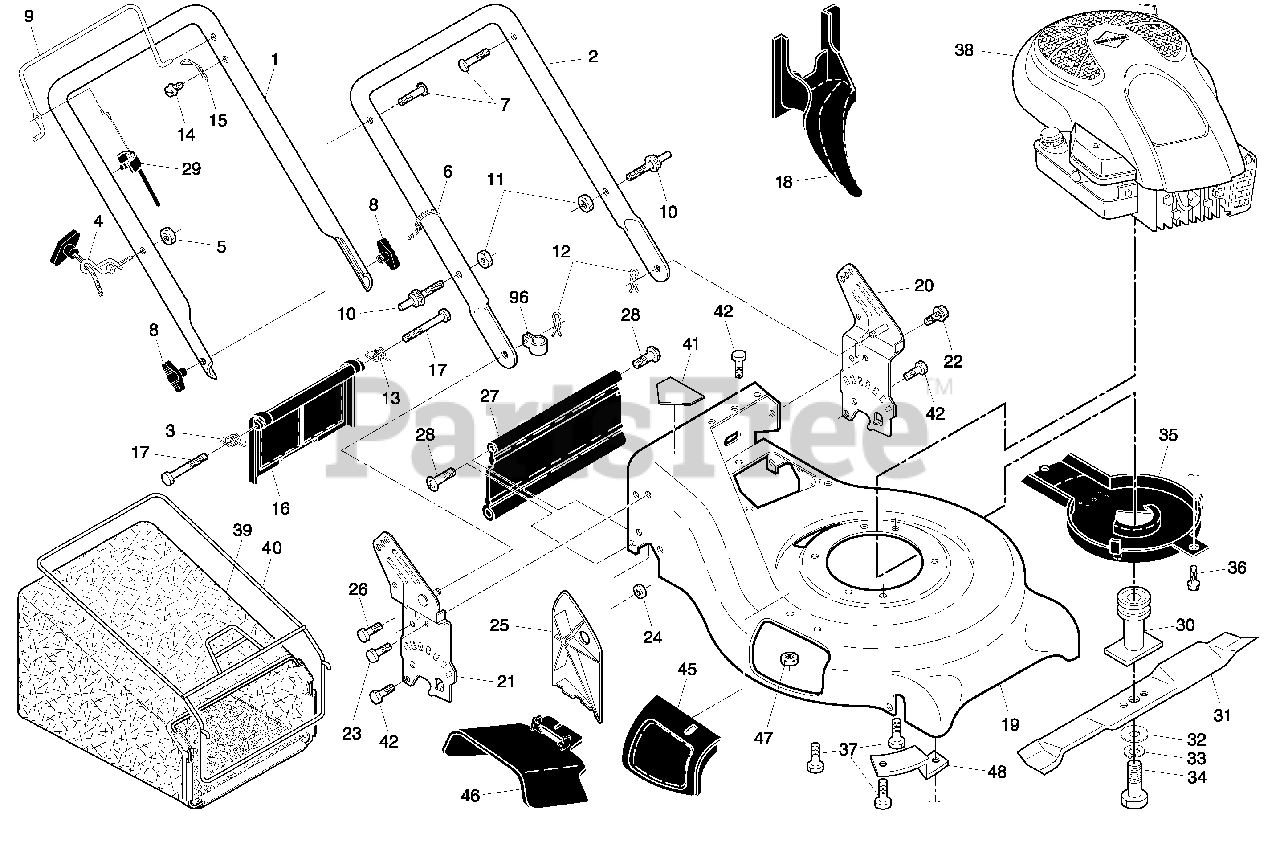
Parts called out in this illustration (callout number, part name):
1	Handle, Upper
2	Handle, Lower
3	Spring, Rear Door, RH
4	Rope Guide
5	Nut, Hex, with Lockwasher Insert 1/4-20
6	Wire, Tie
7	Bolt, Handle 5/16-18 x 2-5/8
8	Knob, Handle
9	Control Bar
10	Pin, Handle
11	Nut, Hex
12	Cotter, Hairpin
13	Spring, Rear Door, LH
14	Screw
15	Bracket, Upstop
16	Rear Door Assembly
17	Bolt, Rear Door
18	Plug, Mulcher
19	Kit, Housing
20	Handle Bracket Asembly, LH
21	Handle Bracket Assembly, RH
22	Screw, Hex Washer Head
23	Bolt, Hex Head 5/16-18 x 5/8
24	Nut, Hex, with Lockwasher Insert 5/16-18
25	Baffl e, Side
26	Screw, Hi-Lo Thread #12 x 5/8
27	Skirt, Rear
28	Screw, Hinge 1/4-20 x 1.25
29	Cable, Operator Presence
30	Blade Adapter / Pulley
31	Blade, 21"
32	Washer
33	Washer, Lock
34	Bolt, Hex Head
35	Debris Shield
36	Bolt
37	Bolt, Engine
39	Grassbag
40	Frame, Grassbag
41	Danger Decal
42	Screw
45	Mulcher Door Assembly
46	Discharge Guard
47	Nut, Hex
48	Mounting Bracket, Debris Shield
96	Clip, Cable
96	Operator's Manual, English
96	Operator's Manual, French
96	Repair Parts Manual, English/French
